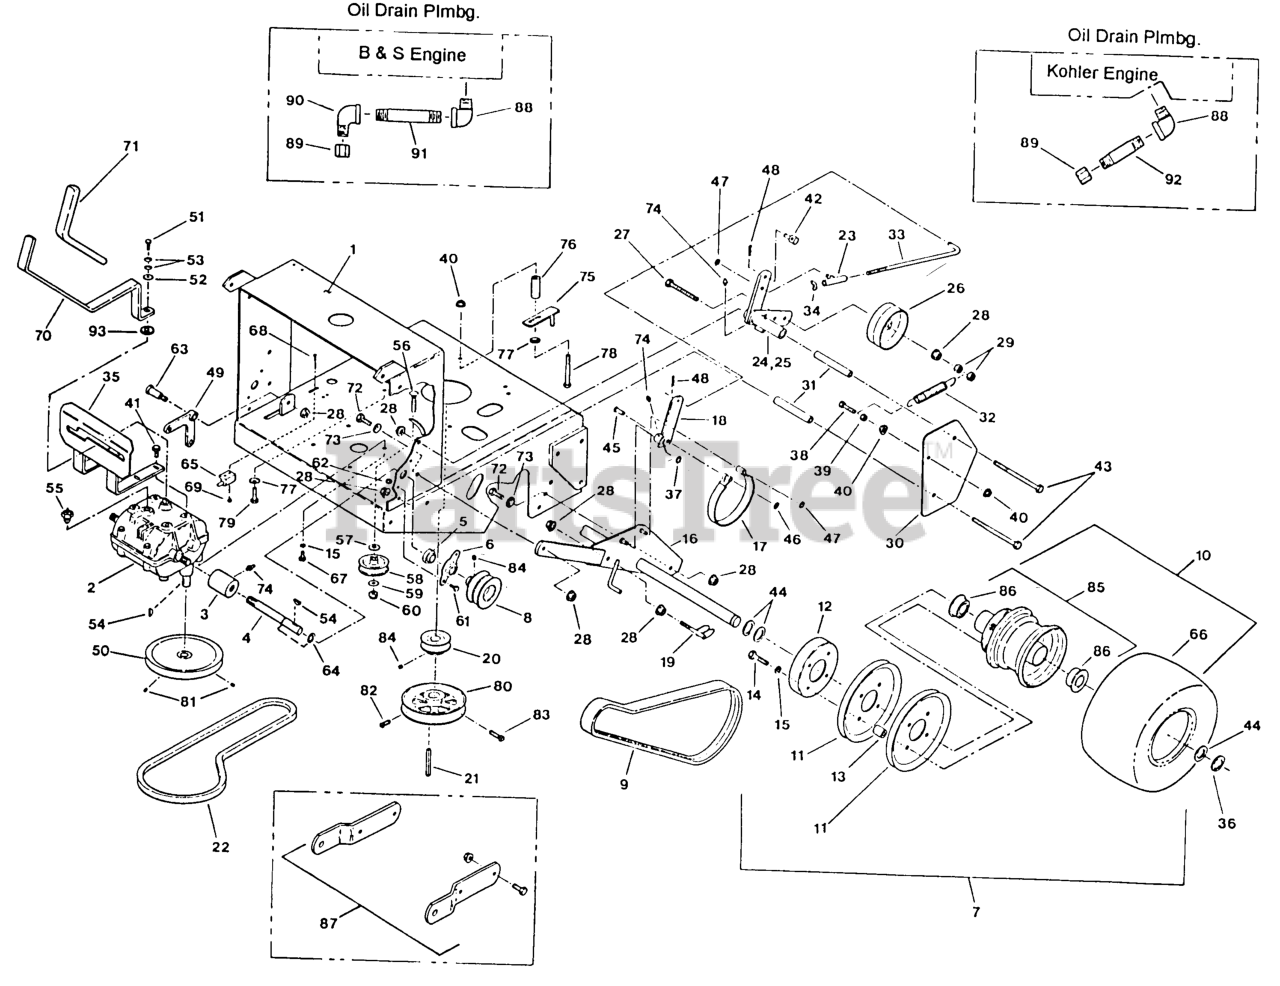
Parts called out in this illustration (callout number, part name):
1	Retainer, Toolkit
5	BEARING-SHAFT
6	FLANGE-OUTPUT
9	BELT,WHEEL DRIVE
11	SHEAVE-WHEEL, DRIVE
12	DRUM-BRAKE
13	SPACER-SHEAVE, WHEEL
15	WASHER-LOCK
17	BAND-BRAKE
20	SHEAVE-TRANSMISSION
21	KEY,MACH 1/4X1/4X2-5/8
22	BELT,TRANS DRIVE
26	IDLER-WHEEL, DRIVE
30	SHIELD-WHEEL, DRIVE
31	SPACER-SHIELD
32	SPRING-EXTENSION
33	ROD-BRAKE
34	WINGNUT-NYLOCK
36	RING-SNAP
42	SWIVEL,SHORT ADJUSTING
44	WASHER-SPACER
45	PIN-CLEVIS
46	RING-RETAIN,PUSH,EXT,FLAT
48	PIN-COTTER
49	BELLCRANK
50	SHEAVE-TRANSMISSION
53	WASHER-SPRING
55	SWITCH-START, NEUTRAL
63	BOLT-SHOULDER
65	SWITCH-OPEN, NORMALLY
75	GUIDE-BELT
77	WASHER-SPRING
78	SCRW,CAP HH M8X1.25X75M
80	SHEAVE,BLADE DRIVE
82	SCREW-SET
84	SCREW-SET
85	WHEEL AND HUB ASM
86	BEARING-FLANGED
87	Sulky Hitch Kit, Metro
88	FITTING-ELBOW-90
89	CAP-HEX
90	ELBOW-90 DEG
91	NIPPLE
92	NIPPLE
